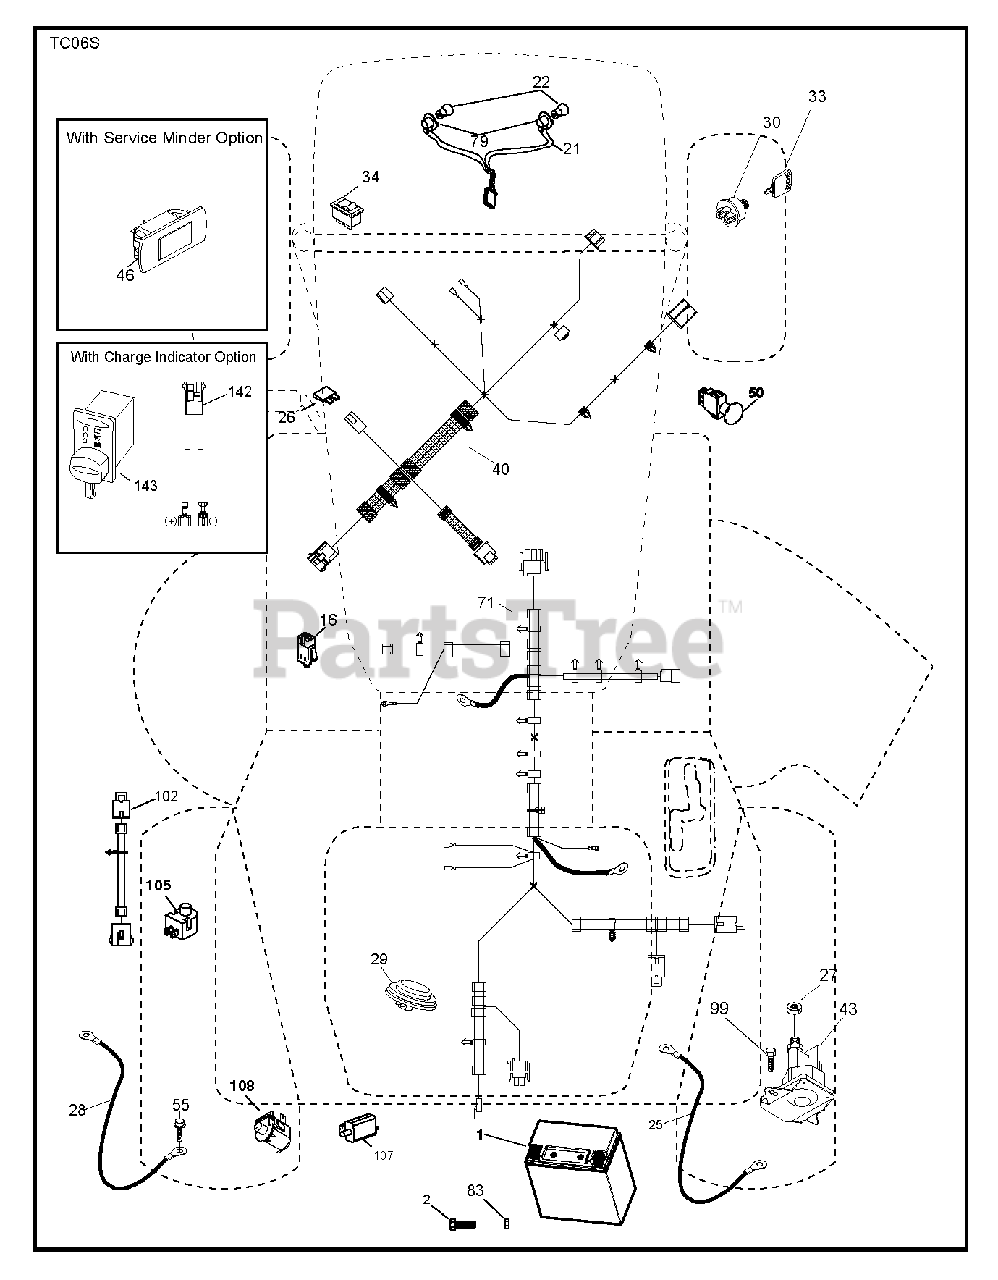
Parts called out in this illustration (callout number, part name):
1	BATTERY BATTERY 14AH 12V LEOC
2	SCREW.HEX.HEAD.CAP.M6 X1.12W
16	SWITCH INTERLOOK PUSH-IN
21	HARNESS.LIGHT W/4152J BULBS
25	CABLE CABLE.RED.20.8AWG.M6.CRD
26	FUSE 20AMP
27	NUT
28	CABLE CABLE.BLACK.20.8AWG.M6.C
29	SWITCH.SEAT.DELTA.OPC.
30	SWITCH.IGN.DELTA.W.LGH.ROS
33	KEY.CHAIN.BLISTER.PACK.GEN.INT
40	HARNESS.DASH.EL.SRD.CRD.RDY.ST
43	SOLENOID.W/BRASS.PLUNGER
46	GUAGE.SRVCMNDR.HRMTR.
50	RB PTO.SWITCH.8 TERMINAL.BLACK
55	SCREW 5/16"
71	HARNESS.CHASS.CRD.TEX.RDY.STRT
79	BULB HOLDER ASM.
83	NUT NUT SQUARE
99	SCREW
102	HARNESS ASSY
105	REVERSE SWITCH
107	.WITCH.FULL BAGGER.INDICATOR
108	SWITCH.SNAPMOUNT.NC
142	CHARGE.PORT.PIGTAIL HARNESS
143	CHARGE.PORT
